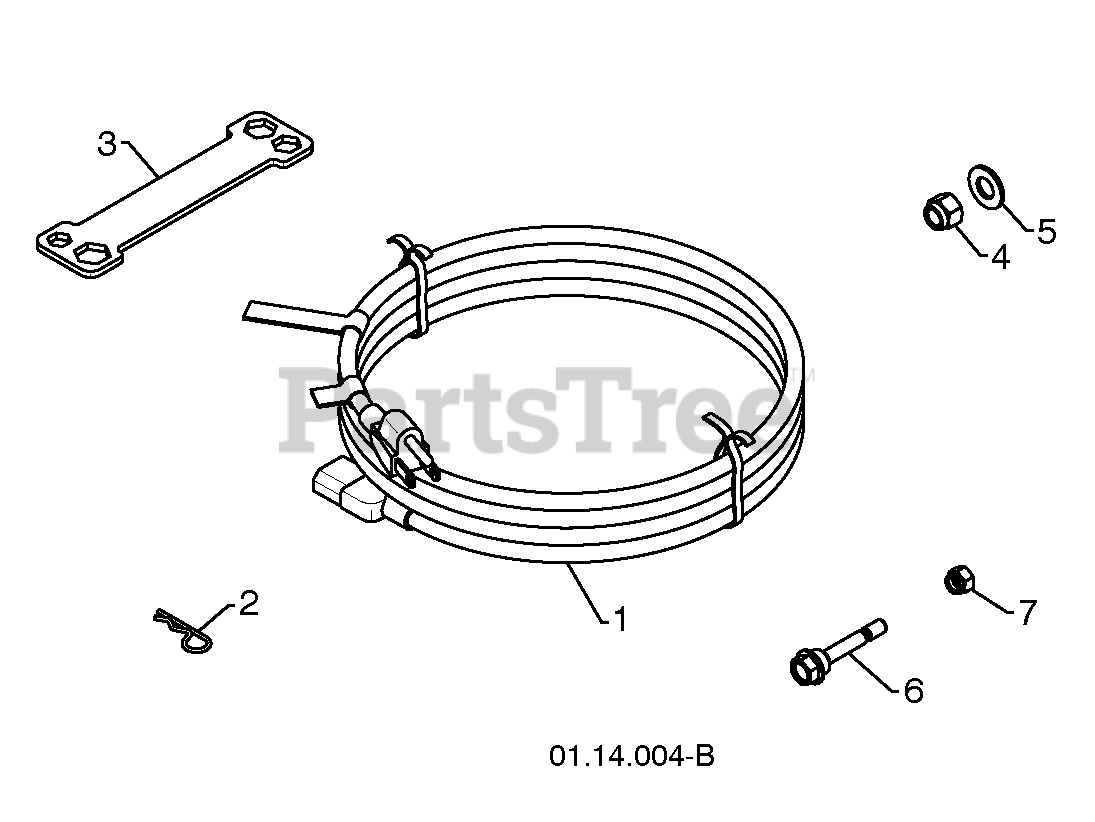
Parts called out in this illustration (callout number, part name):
1	POWER CORD
2	RETAINER PIN
3	WRENCH
4	LOCKNUT 3/8-16
5	WASHER 3/8
6	SHEAR BOLT 1/4-20 X 1-3/4
7	LOCKNUT 1/4-20
